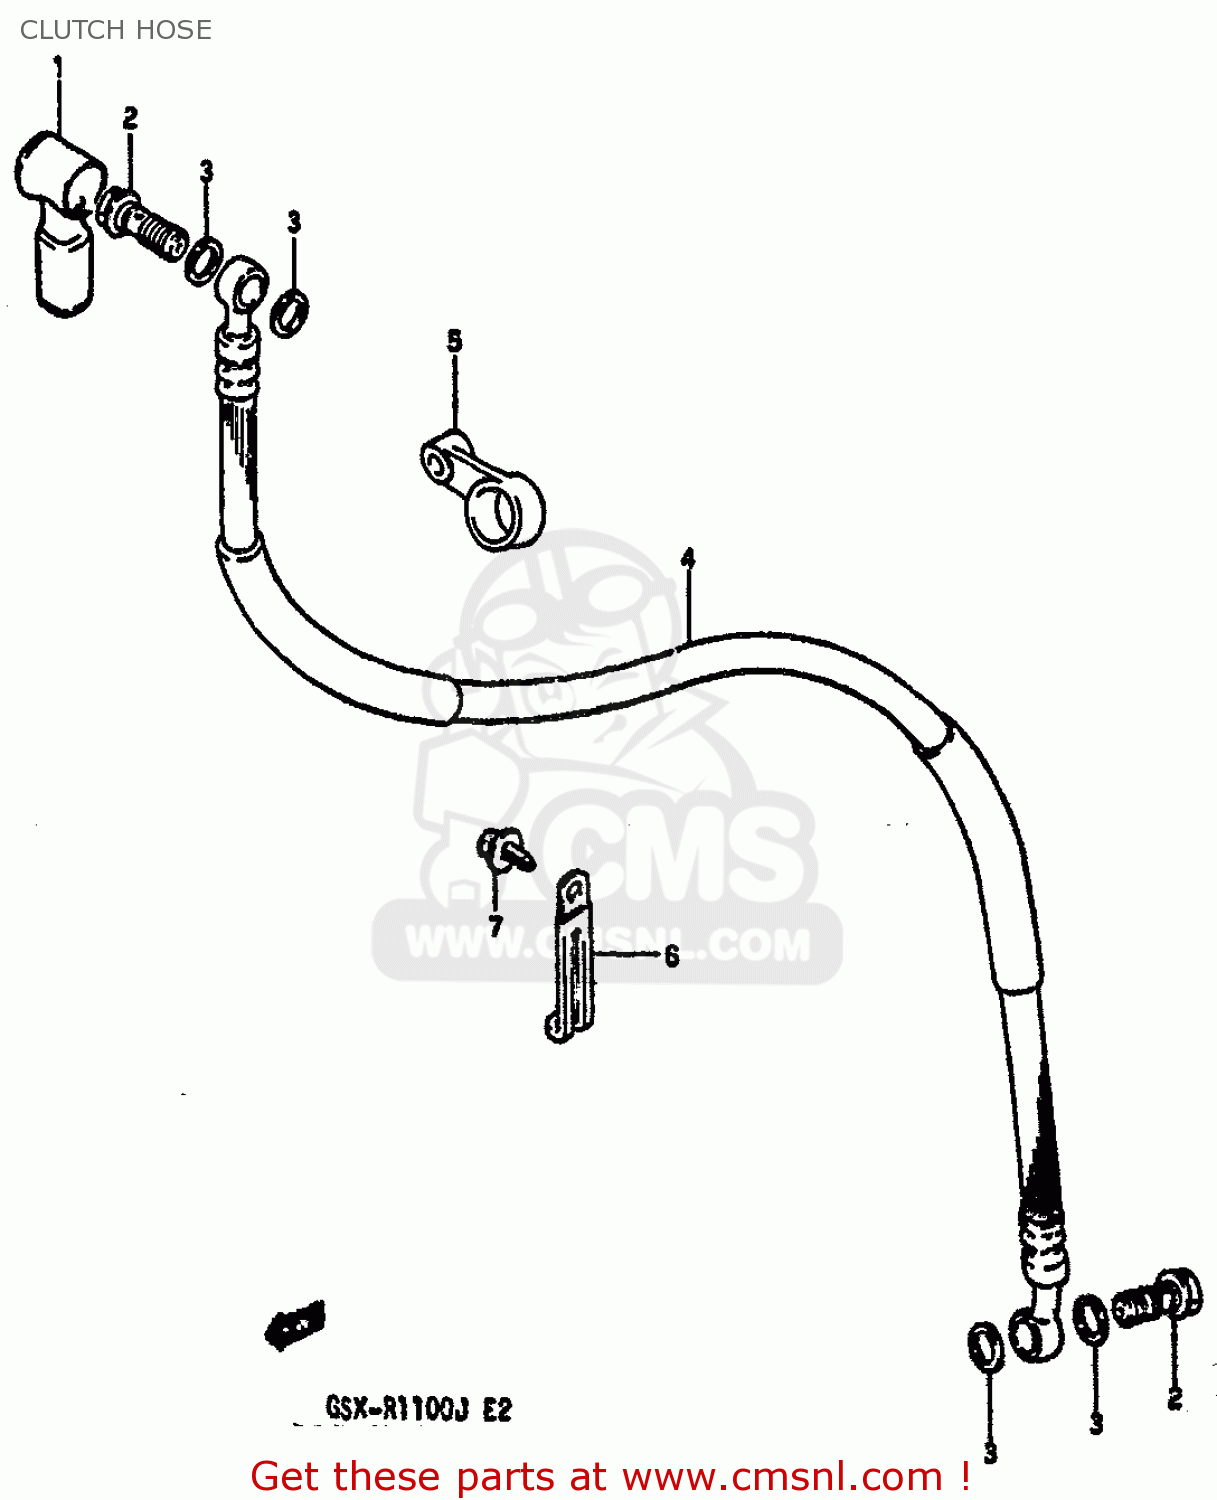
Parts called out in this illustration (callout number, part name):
1	BOOT,MASTER CYLINDER
2	BOLT UNION
3	WASHER(10X15X1.5)
4	HOSE,CLUTCH
5	CLAMP,CLUTCH HOSE NO.2
6	CLAMP
7	CLIP
